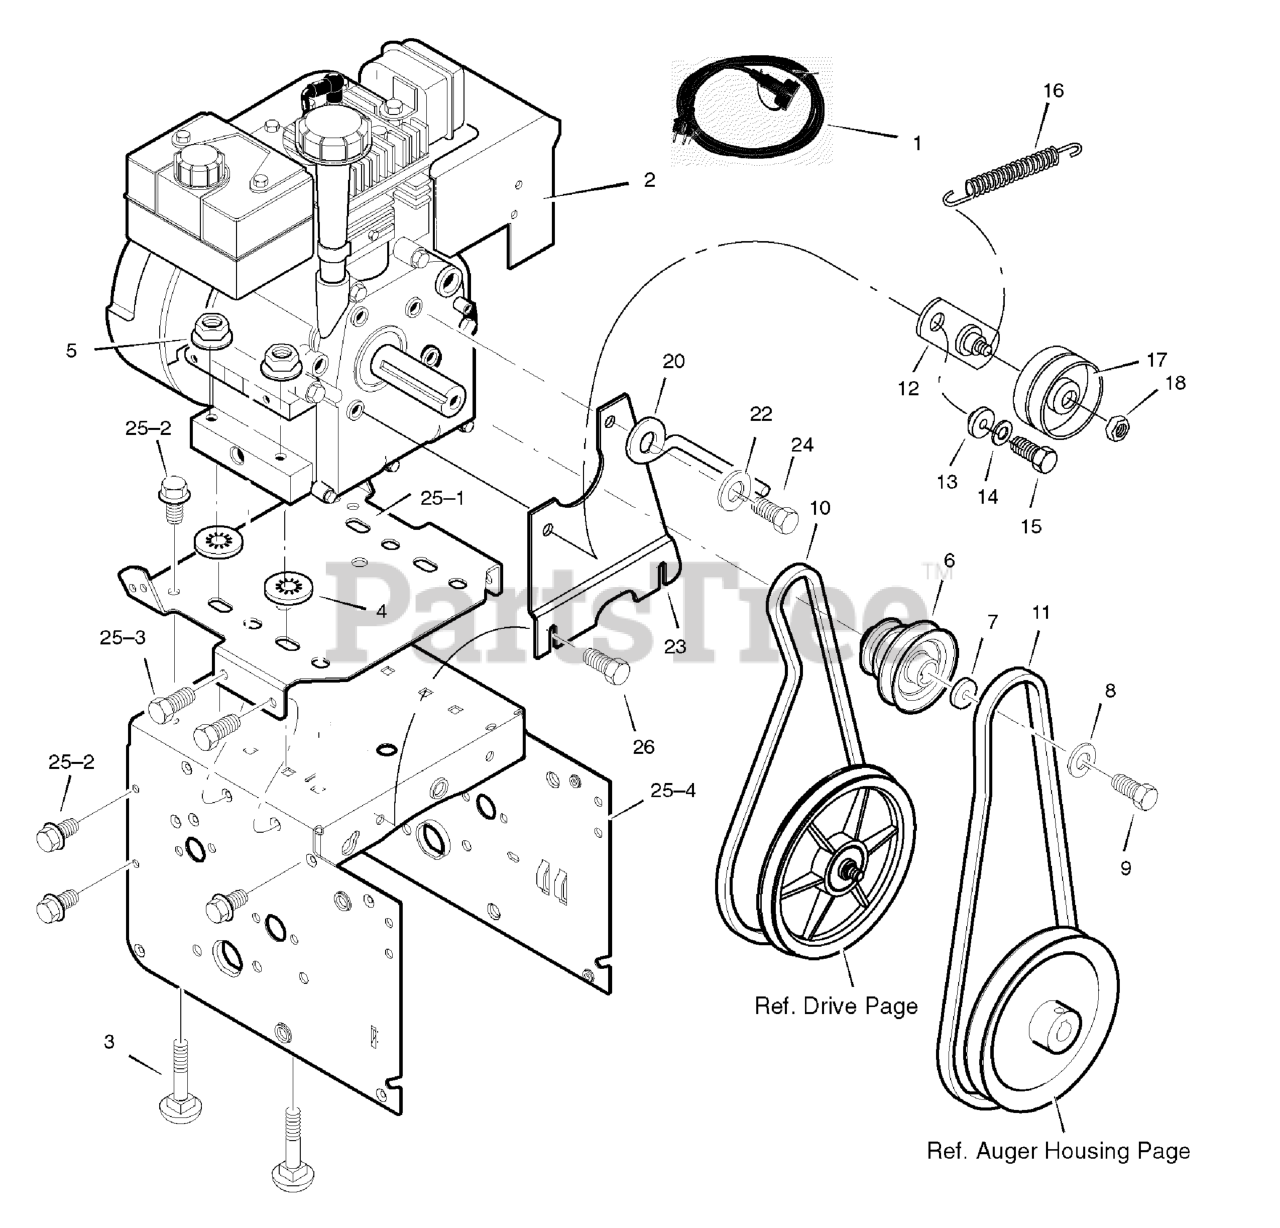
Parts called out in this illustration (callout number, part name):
1	CORD, Electric, 10FT. 110V
2	ENGINE *
3	BOLT, CARRIAGE 5/16-18
4	RETAINER, PUSH
5	NUT, Hex Flange ESNA, 5/16-18
6	PULLEY, ENGINE
7	WASHER
8	WASHER .38ID
9	SCREW, 3/8-24 x 1.00
10	V-BELT, Traction Drive, 3L 33.13
11	BELT, Auger, V4L 38.35
12	BRACKET ASSEMBLY, IDLER
13	BUSHING, IDLER BRACKET
14	WASHER, SPLIT
15	SCREW 5/16-24 X 1.00
16	SPRING, IDLER TRACTION DRIVE
17	PULLEY, IDLER
18	NUT, JAM 3/8-16
20	GUIDE, BELT
22	WASHER, SPTLK .31X.58X.08
23	PLATE, ANTI VIBRATION
24	SCREW, 5/16-24 x 1.00
25	FRAME ASSEMBLY
25-1	PLATE, ENGINE MOUNT
25-2	SCREW, TAP 1/4-20 X .63
25-3	SCREW, TAP 5/16-18 X .50
25-4	FRAME, MOTOR BOX
